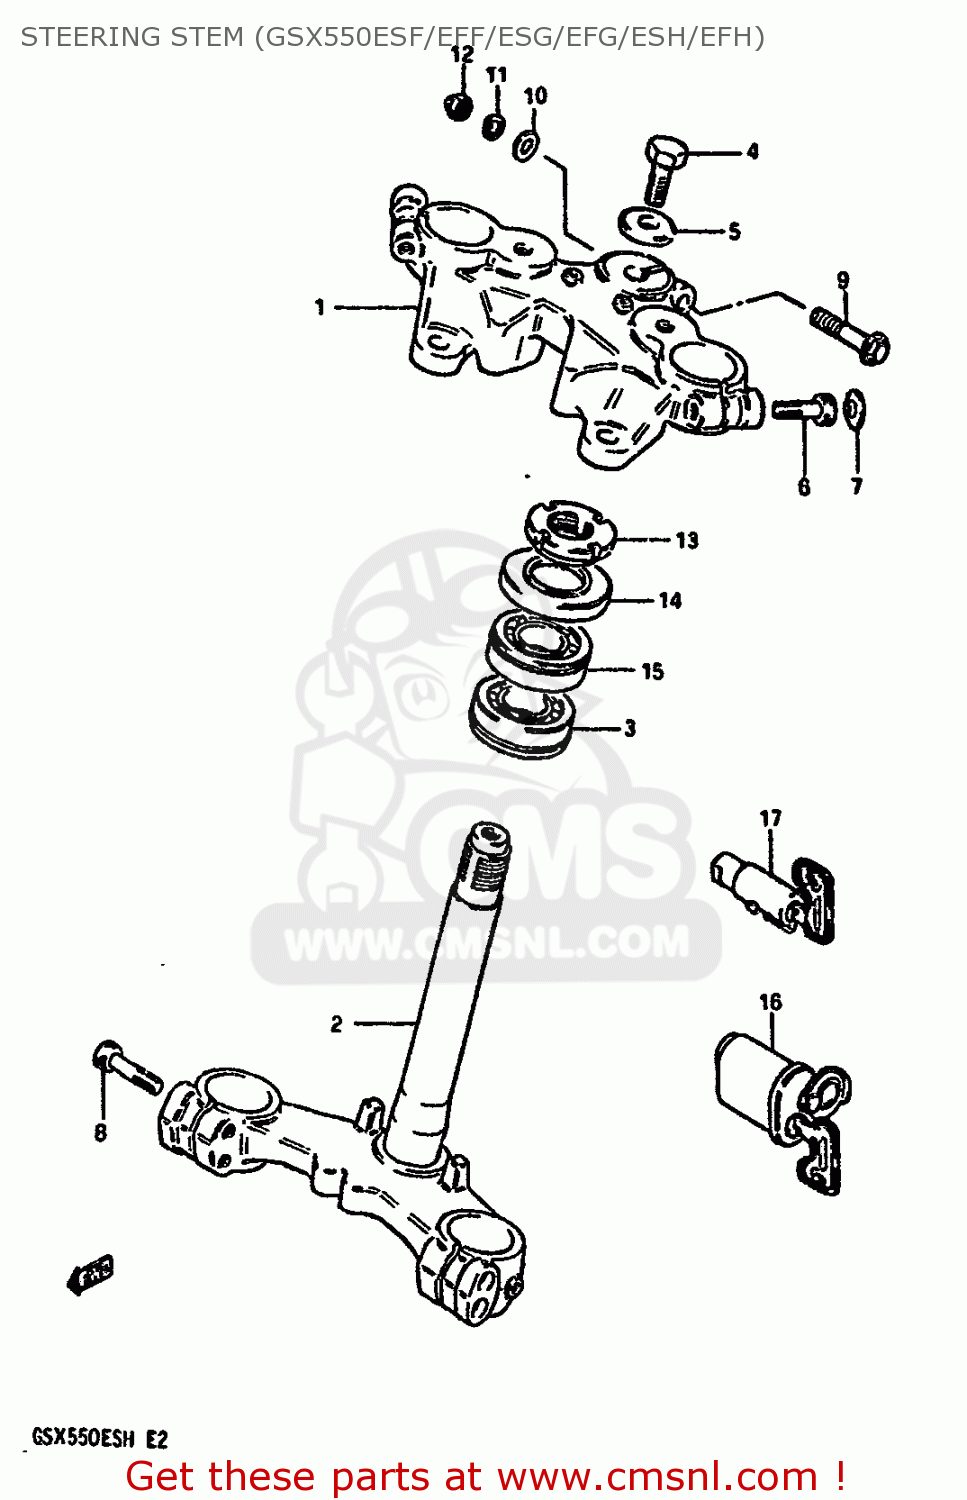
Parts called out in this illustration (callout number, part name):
1	HEAD,STEERING STEM
2	STEM,STEERING
3	BEARING
4	NUT,STEM HEAD
5	WASHER,STEERING STEM B
6	BOLT,FORK INNER TUBE FITTING
7	CAP(OD:20)
8	BOLT, REAR (8X30)
9	BOLT, UPPER
10	WASHER
11	WASHER,LOCK,8.
12	NUT,M8X1.25X12
13	NUT,STEERING STEM
14	DUST SEAL,STEERING UPR
15	TAPER,ROLLER BEARING
16	LOCK ASSY, STEERING (NEIMAN TYPE EXECUTE
17	LOCK ASSY,STEERING(NEIMAN)
